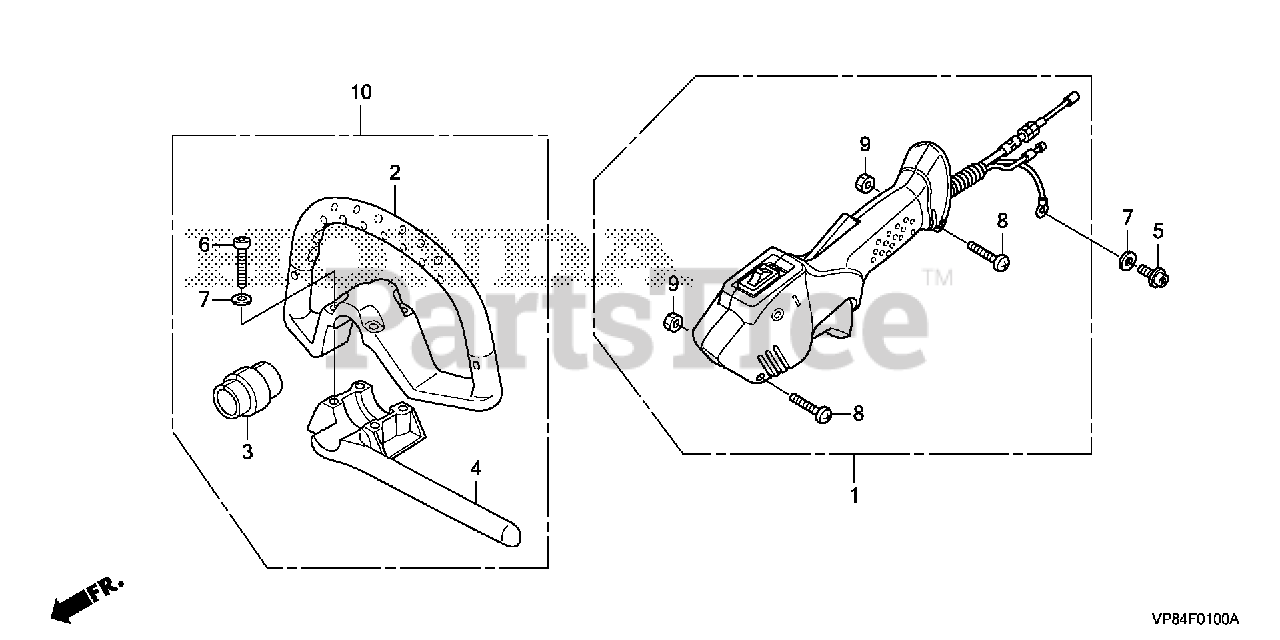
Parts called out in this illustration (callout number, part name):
1	LEVER ASSY., THROTTLE (FOR U.S.A.)
2	HANDLE, LOOP
3	RUBBER, LOOP HANDLE
4	BAR, LOOP HANDLE
5	BOLT, TORX (5X10)
6	BOLT, TORX (5X35)
7	WASHER (5MM)
8	SCREW, PAN (5X20)
9	NUT, HEX. (5MM)
